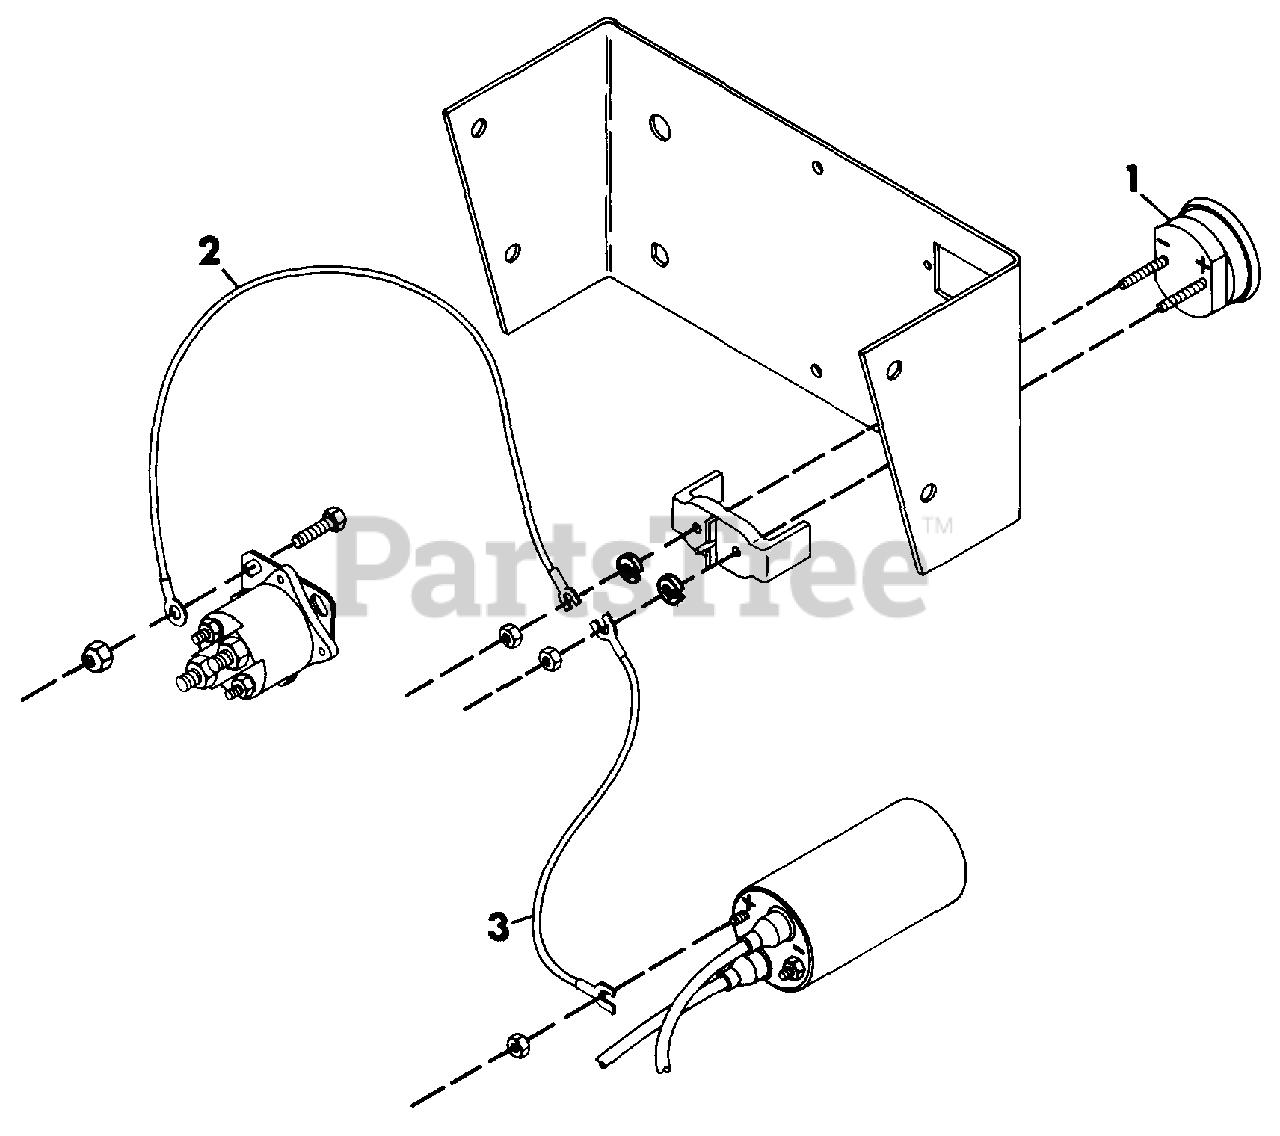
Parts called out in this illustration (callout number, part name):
1	GAUGE, VOLTMETER
2	WIRE, VOLTMETER
3	WIRE, VOLTMETER
